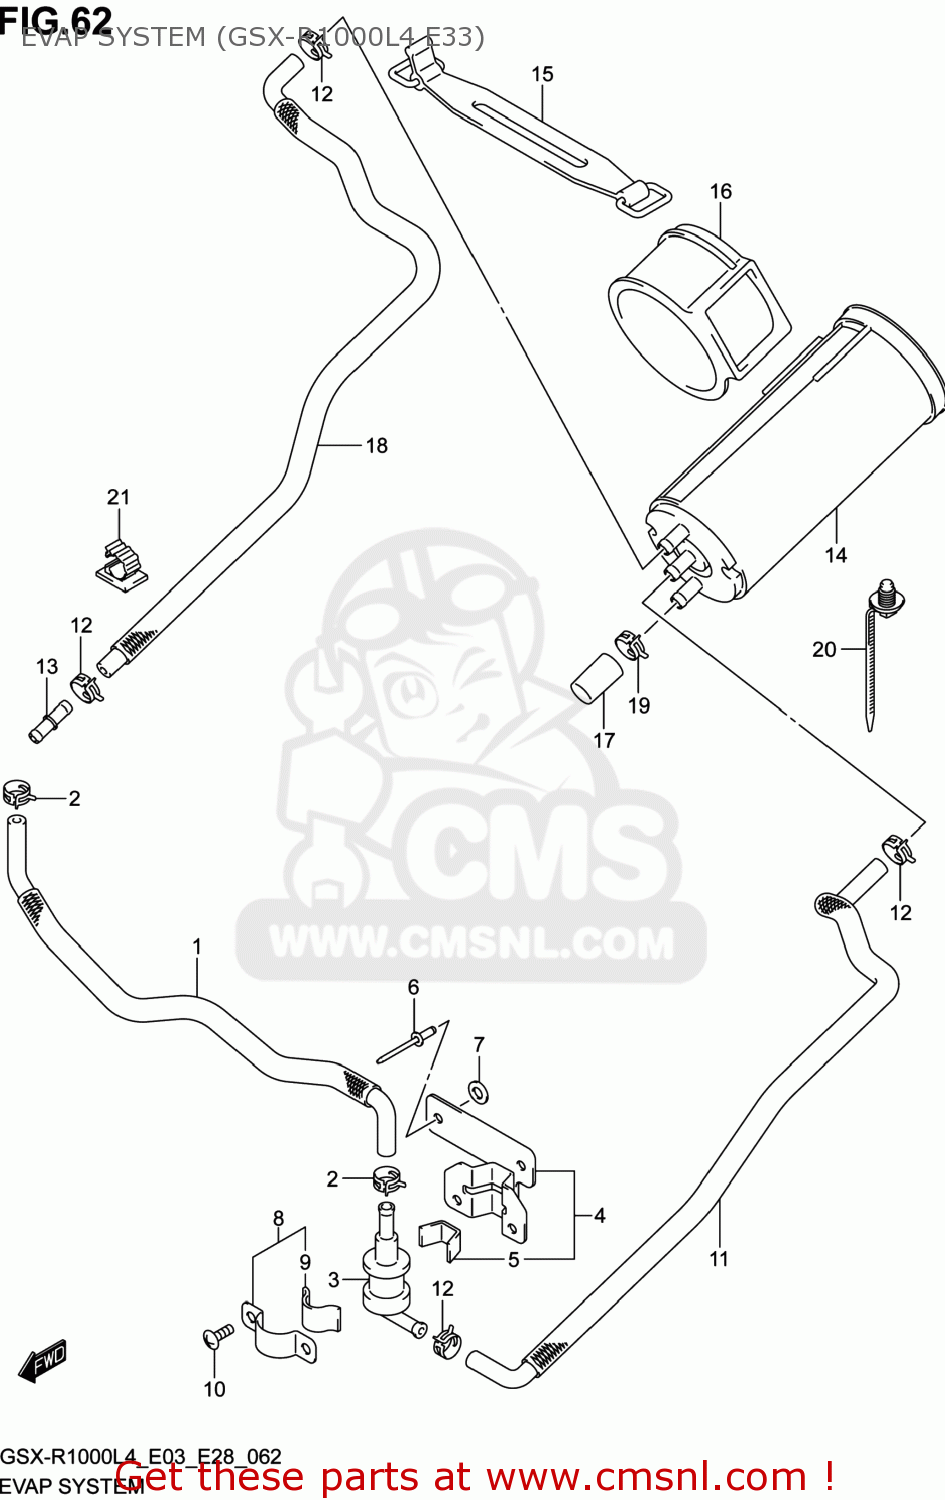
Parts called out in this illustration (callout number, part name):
1	HOSE,TANK & BREATHER VALVE
2	CLIP
3	VALVE,FUEL TANK BREATHER
4	PLATE,BREATHER VALVE
5	CUSHION
6	RIVET
7	WASHER
8	PLATE,FUEL TANK BREATHER NO.2
9	CUSHION
10	SCREW
11	HOSE,CSTR & BREATHER VALVE
12	CLIP
13	JOINT
14	CANISTER ASSY,CHARCOAL
15	BAND,CANISTER
16	CUSHION,CANISTER
17	CAP
18	HOSE,CSTR PURGE
19	CLIP
20	CLAMP(L:154)
21	CLAMP
